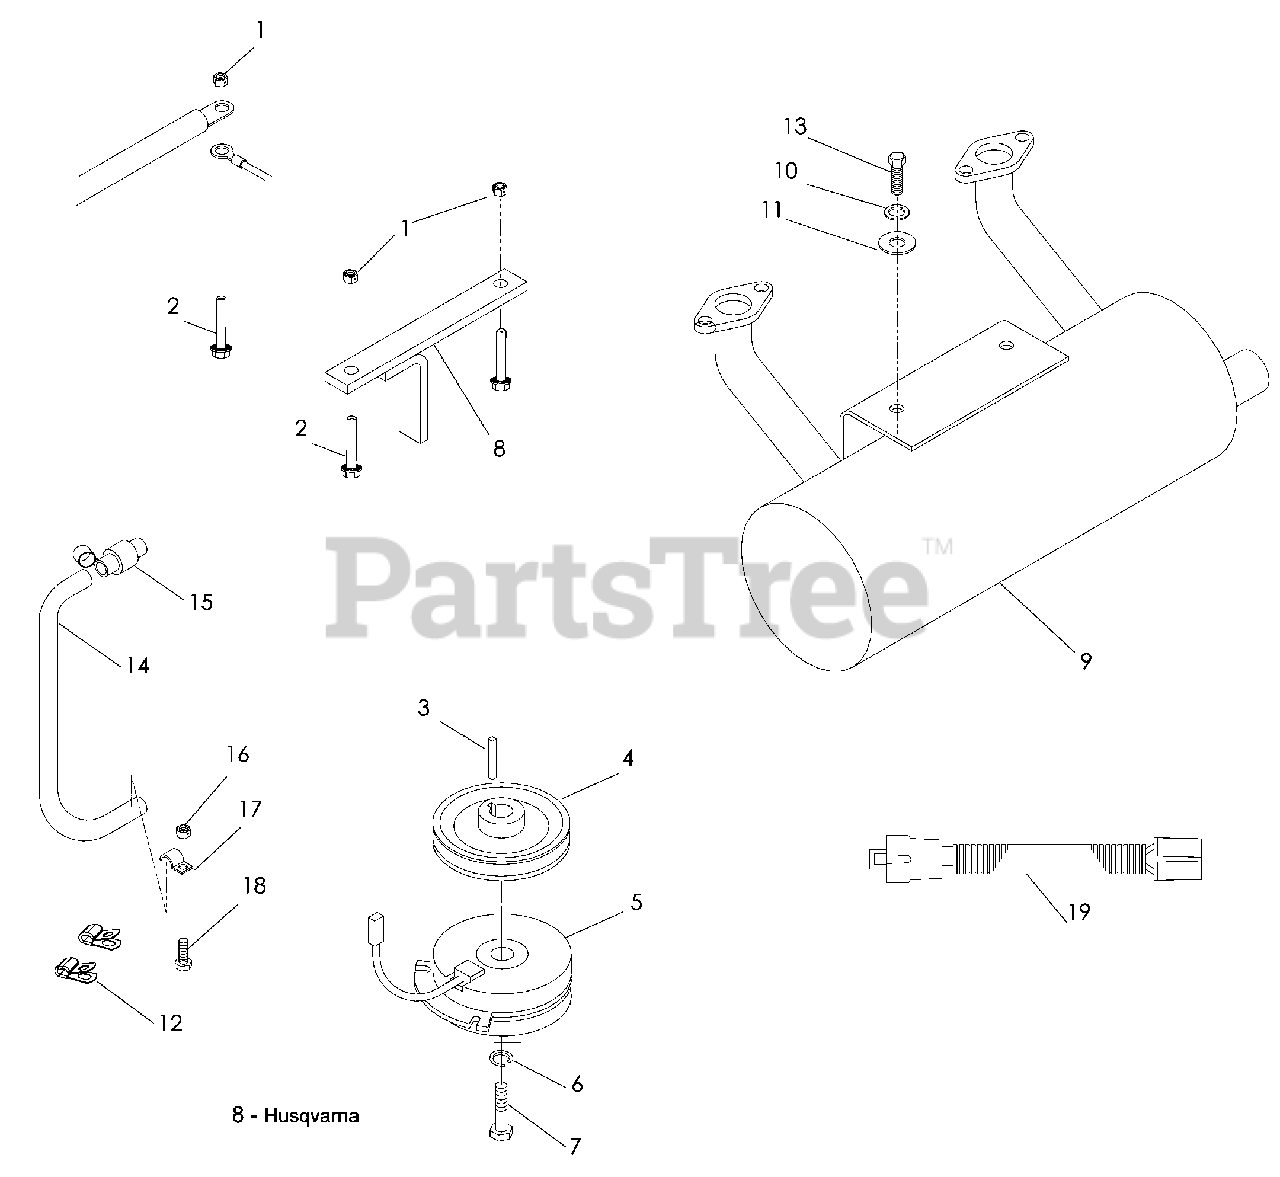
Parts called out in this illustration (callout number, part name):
1	NUT 5/16-18 CENTERLOCK
2	HCS 5/16 x 1¾ SERRATED
6	LOCKWASHER 7/16
7	HCS 7/16 x 2½
8	TIE DOWN, CLUTCH
10	LOCKWASHER 5/16
11	WASHER 5/16 STD FLT
12	CLAMP, DOUBLE TUBE
13	HCS 5/16-18 x ¾
14	OIL DRAIN HOSE
15	OIL DRAIN FITTING
16	NUT ¼-20 CENTERLOCK
18	HCS ¼- 20 x ¾
